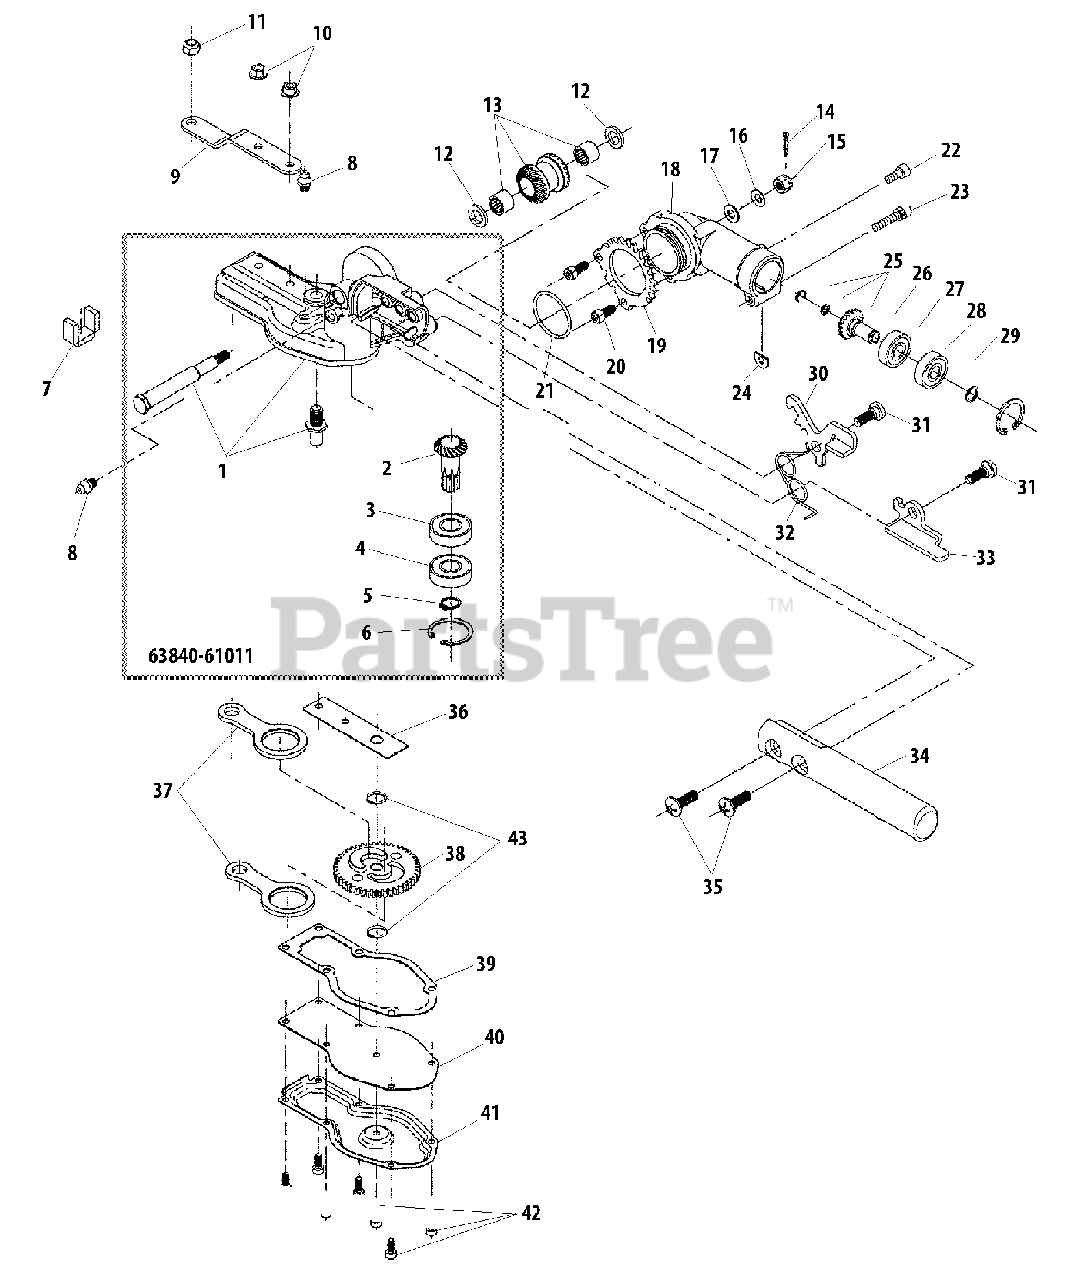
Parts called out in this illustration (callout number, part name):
1	CASE, GEAR - LOWER
2	GEAR - SHAFT
3	BEARING, BALL - 6001
4	BEARING, BALL - 6001ZZ
5	RING, RETAINING - 12
6	RING, RETAINING - 28
7	SEAL, FELT
8	FITTING, GREASE
9	BRACKET, CUTTER
10	NUT - 5 -- FLANGE
11	LOCKNUT - 6
12	COLLAR
13	GEAR SET - BEVEL
14	PIN, SPLIT
15	NUT - CASTLE
16	WASHER - CONICAL
17	WASHER - 6
18	CASE, GEAR - UPPER
19	PLATE, ADJUST
20	SCREW - 5X12
21	O-RING
22	SCREW - 5X12
23	SCREW - 5X25
24	SHIM
25	GEAR - BEVEL
26	BEARING, BALL - 609
27	BEARING, BALL - 609ZZ
28	RING, RETAINING
29	RING, RETAINING - 24
30	LEVER, LOCK
31	SCREW
32	SPRING
33	LEVER, LOCK
34	HANDLE
35	SCREW - 6X20
36	PLATE, GUIDE
37	ROD, CONNECTING
38	CAM GEAR
39	GASKET
40	PLATE, GEAR CASE
41	CASE, GEAR - LOWER
42	SCREW - 4X10
43	SPACER
63840-61011	GEAR CASE ASSY
